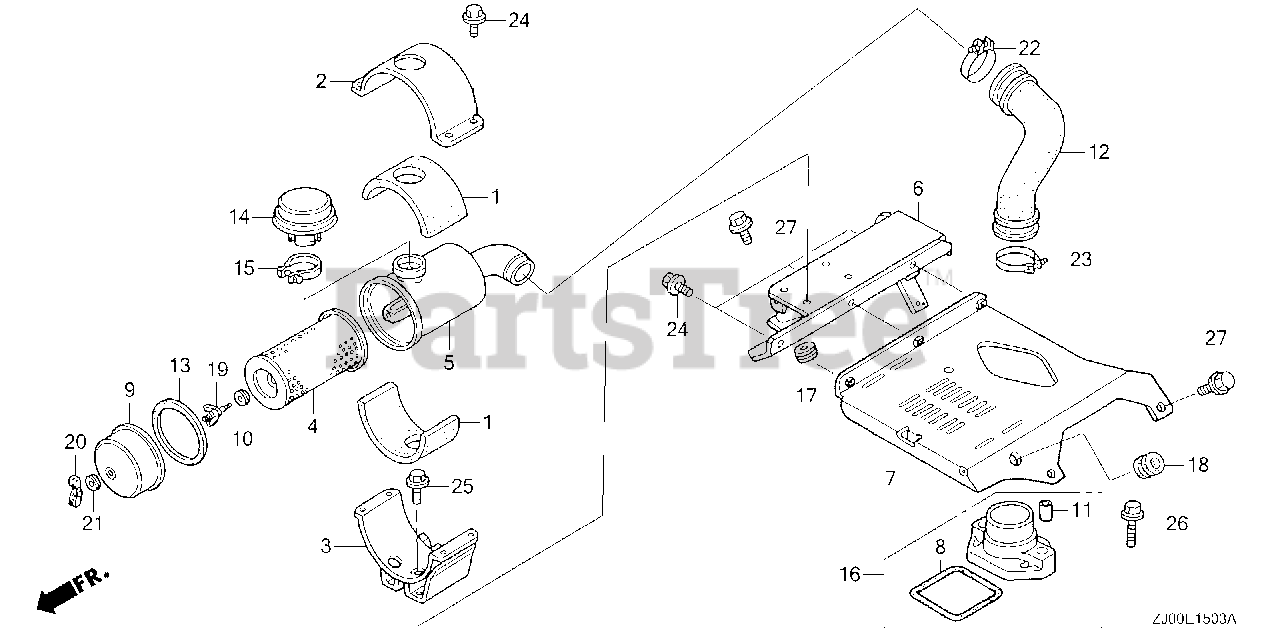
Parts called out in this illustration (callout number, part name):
1	RUBBER, AIR CLEANER HOLDER (UPPER)
2	HOLDER, AIR CLEANER (UPPER)
3	HOLDER, AIR CLEANER (LOWER)
4	ELEMENT, AIR CLEANER
5	HOUSING, AIR CLEANER (SNORKEL)
6	STAY A, AIR CLEANER (SNORKEL)
7	STAY B, AIR CLEANER (SNORKEL)
8	SEAL, AIR CLEANER HOUSING
9	COVER, AIR CLEANER
10	WASHER, AIR CLEANER
11	COLLAR A, AIR CLEANER
12	TUBE, AIR CLEANER CONNECTING
13	SEAL, AIR CLEANER
15	CLAMP ASSY.
16	JOINT ASSY., CONNECTING TUBE (B)
17	GROMMET, RESERVE TANK
19	BOLT, AIR CLEANER
20	WINGNUT (6MM) (BLACK)
21	GROMMET, AIR CLEANER
22	BAND, AIR CLEANER CONNECTING TUBE (52)
23	BAND, AIR CLEANER CONNECTING TUBE (58)
24	BOLT, FLANGE (6X12)
25	BOLT, FLANGE (6X16)
26	BOLT, FLANGE (6X28)
27	BOLT, FLANGE (8X20)
